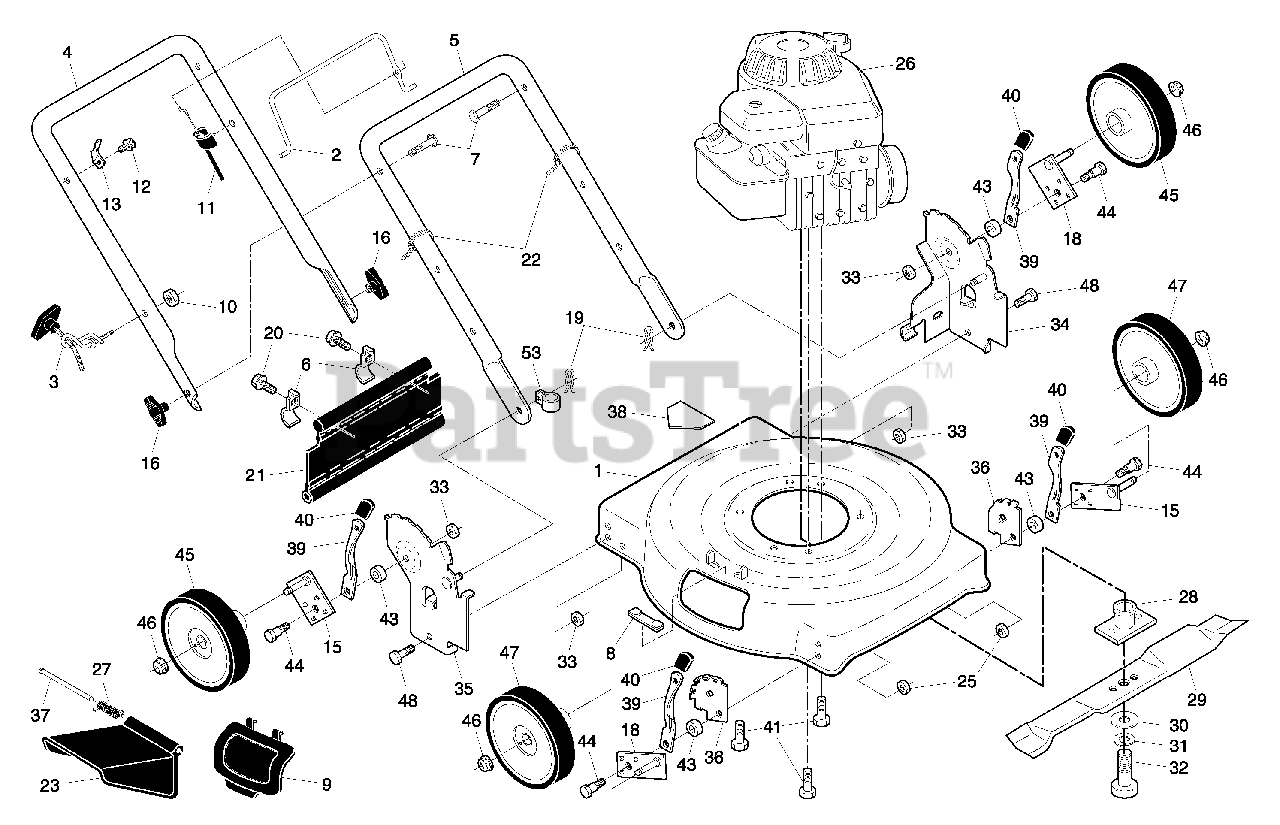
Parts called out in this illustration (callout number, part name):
1	Lawn Mower Housing Assembly
2	Control Bar
3	Rope Guide
4	Upper Handle
5	Lower Handle
6	Hinge Bracket
7	Handle Bolt 5/16-18
8	Clip, Closeout
9	Mulcher Plate
10	Locknut, Hex 1/4-20
11	Engine Zone Control Cable
12	Screw, Hex Head, Threaded, Rolled #10-24 x1/2
13	Up-Stop Bracket
15	Axle Arm Assembly (Rear, RH / Front, LH)
16	Handle Knob
18	Axle Arm Assembly (Rear, LH / Front, RH)
19	Hairpin Cotter
20	Screw
21	Rear Deflector
22	Wire Tie
23	Discharge Guard
25	Nut, Hex
27	Torsion Spring
28	Blade Adapter
29	22" Blade
30	Hardened Washer
31	Helical Lockwasher 3/8
32	Hex Head Screw 3/8-24 x 1/4 Grade 8
33	Nut, Hex, Centerlock 5/16-18
34	Support, Wheel Bracket, LH
35	Support, Wheel Bracket, RH
36	Adjuster, Wheel Bracket
37	Hinge Rod
38	Danger Decal
39	Selector Spring
40	Selector Knob
41	Screw, Hex Head, Threaded, Rolled 3/8-16 x 1
43	Washer
44	Shoulder Bolt
45	Wheel & Tire Assembly, Rear, 8"
46	Locknut, Hex 3/8-16
47	Wheel & Tire Assembly, Front, 7"
48	Screw, Hex Head, Serrated, Type TT 1/4 x 20
53	Clip, Cable
